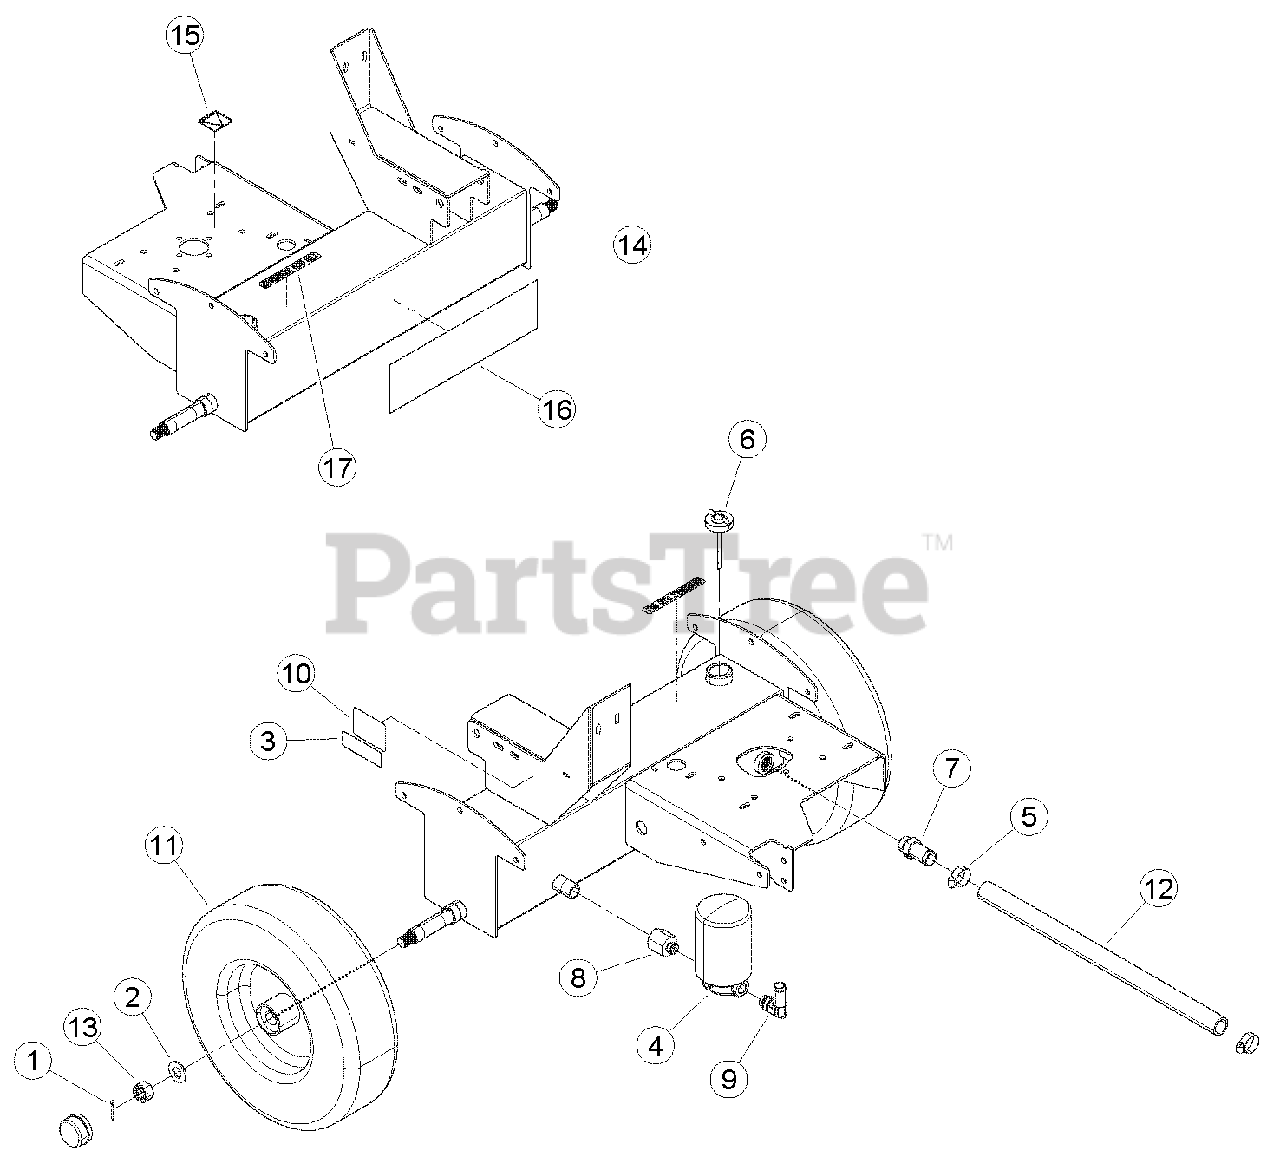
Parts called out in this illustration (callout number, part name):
1	PIN, 5/32 X 1-1/4 COTTER ZP
2	WASHER, 3/4 SAE FLAT ZP
3	DECAL, SERIAL NUMBER
4	FILTER, SPIN-ON
5	CLAMP, 1-1/4" HOSE
6	CAP, W/DIPSTICK
7	ADAPTER, 1" HOSE BEAD X -12 MORING
8	ADAPTER, -8 MORING / -12 FMNPT
9	ADAPTER, -8 MORING / 3/4" HOSE BARB
10	DECAL, 4.80-8 LOAD RATING
11	ASSEMBLY, TIRE 4.8-8
12	HOSE, 1.00 ID X 22 IN 100R4 HYD
13	NUT, SLOTTED 3/4-16 GRADE 2
14	WELDMENT, LOG SPLITTER TANK, SERVICE PART
15	DECAL, SHIELD DANGER ISO
16	DECAL, ECHO BEARCAT 14.12 X 4.00
17	DECAL, HYDRAULIC FLUID
